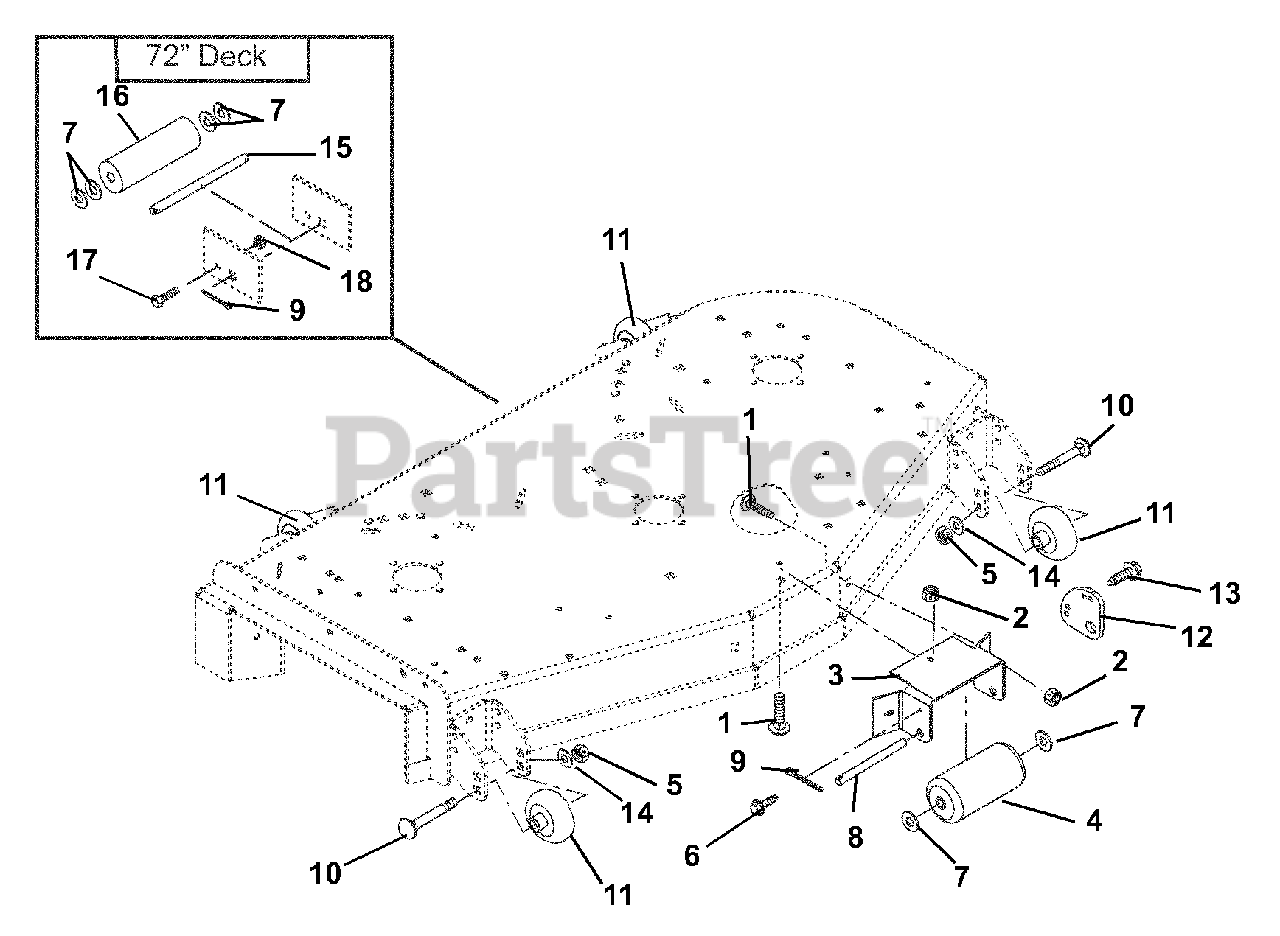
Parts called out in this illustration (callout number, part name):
1	Bolt-Round Head Square Neck .38-16 x 1.00 Grade 5
2	Nut-Locking-Top-Flange .38-16
3	Bracket- Anti-Scalp Roller
5	Nut-Locking-Nylon .50-13
6	Screw-Tapping .25-20 x .75 Hex Washer Head
7	Washer-Flat-Steel .656 x 1.31 x .095
9	Pin-Cotter .25 x 2.00
10	Bolt-Round Head Square Neck .50-13 x 5.00 Grade 2
11	Wheel, 3 x 5
12	Anti-Scalp Washer
13	Screw-Tapping .25-20 x .62 Hex Washer Head
14	Washer-Flat-Steel .531 x 1.06 x .095
15	Shaft, Center Roller
16	Roller, Gage
17	Bolt-Hex .25-20 x .75 Grade 5
18	Nut-Locking-Center .25-20
